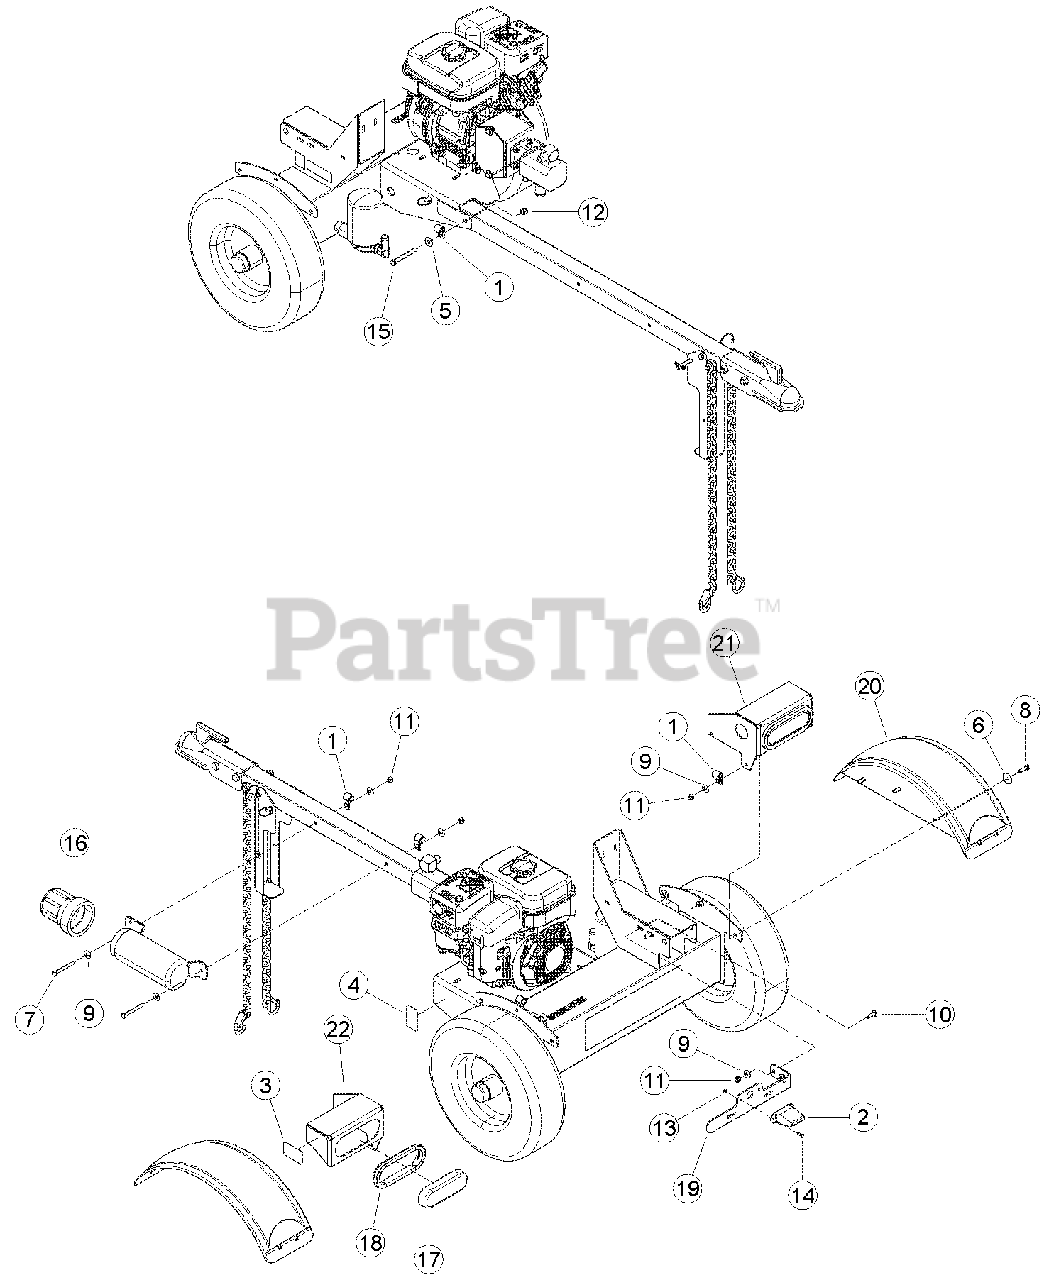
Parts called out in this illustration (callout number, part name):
1	CLAMP, 9/16" COATED
2	LIGHT, LICENSE PLATE
3	REFLECTOR, WIDE ANGLE RED
4	REFLECTOR, WIDE ANGLE AMBER
5	WASHER, 3/8 FLAT ZP
6	WASHER, 5/16 FENDER ZP
7	BOLT, 5/16 X 3 HEX HD GR5 ZP
8	BOLT, 5/16 X 1 HES HD GR5 NC ZP
9	WASHER, 5/16 FLAT ZP
10	BOLT, 5/16 X 1 CRG GR5 ZP
11	NUT, 5/16 NE NYLOCK ZP
12	NUT, 3/8 NE NYLOCK ZP
13	NUT, 10/24 NYLOCK TYPE NM, ZP
14	MACH. SCREW, #10-24 X 3/4 PAN HD PH ZP
15	BOLT, 3/8 X 3-1/4 HEX HD GR5 ZP
16	CONTAINER, MANUAL
17	TAIL LIGHT, OVAL LED
18	GROMMET, OVAL TAIL LIGHT
19	ANGLE, LICENSE
20	FENDER, BLACK PLASTIC DRILLED
21	BRACKET, RIGHT TAIL LIGHT
22	BRACKET, LEFT TAIL LIGHT
